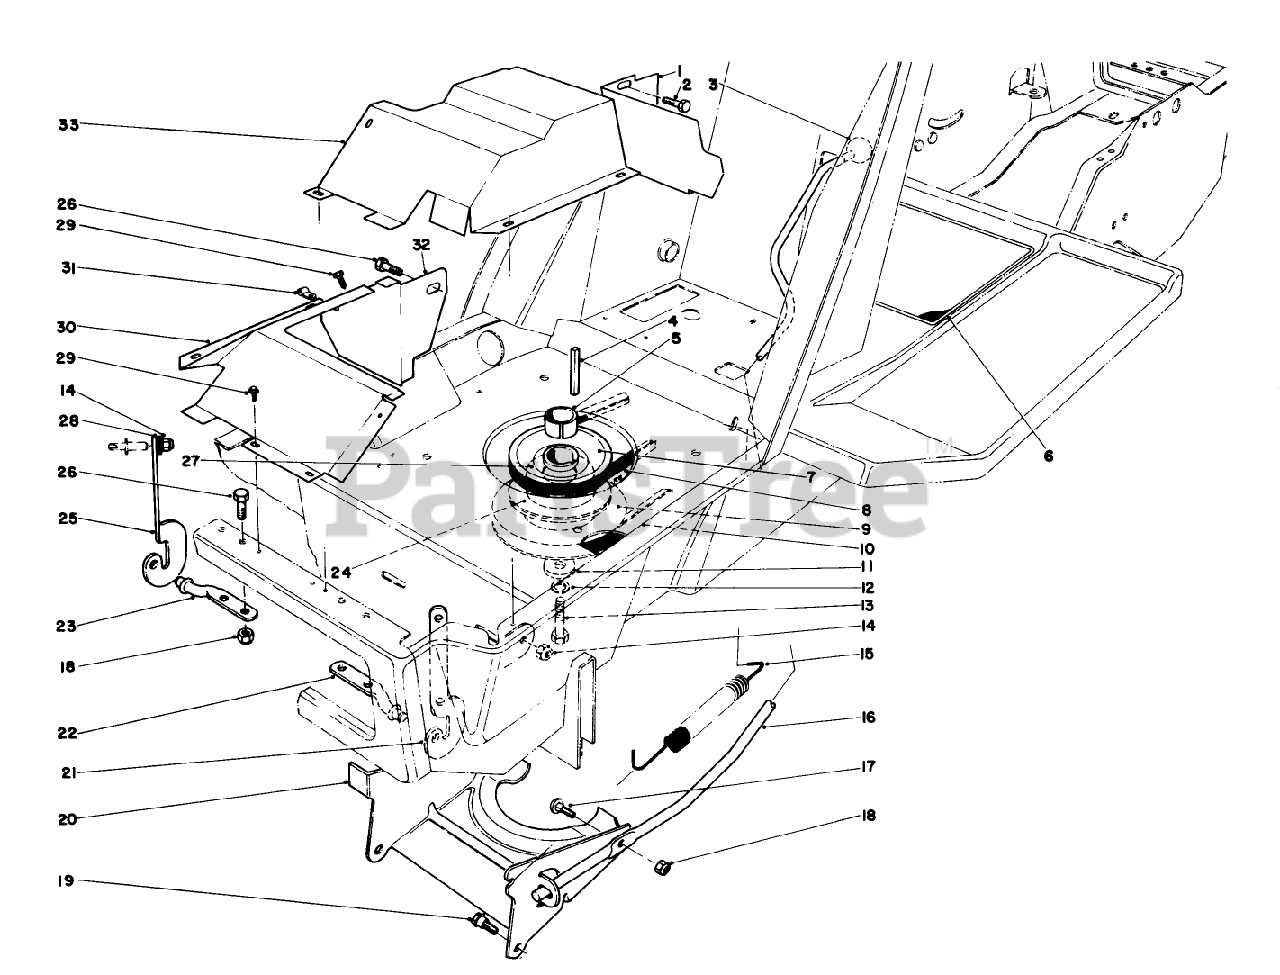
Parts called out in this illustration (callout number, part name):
2	SCREW-HH
4	KEY-SQUARE
8	V BELT
11	WASHER
12	WASHER-LOCK
14	NUT-LOCK, CONE
15	TRACTION SPRING
18	NUT-LOCK, CONE
19	SCREW-SHOULDER
21	L.H. HINGE BRACKET
25	RH HINGE BRKT
26	SCREW-HH
27	SPRING WASHER
29	SCREW-HWHTF
